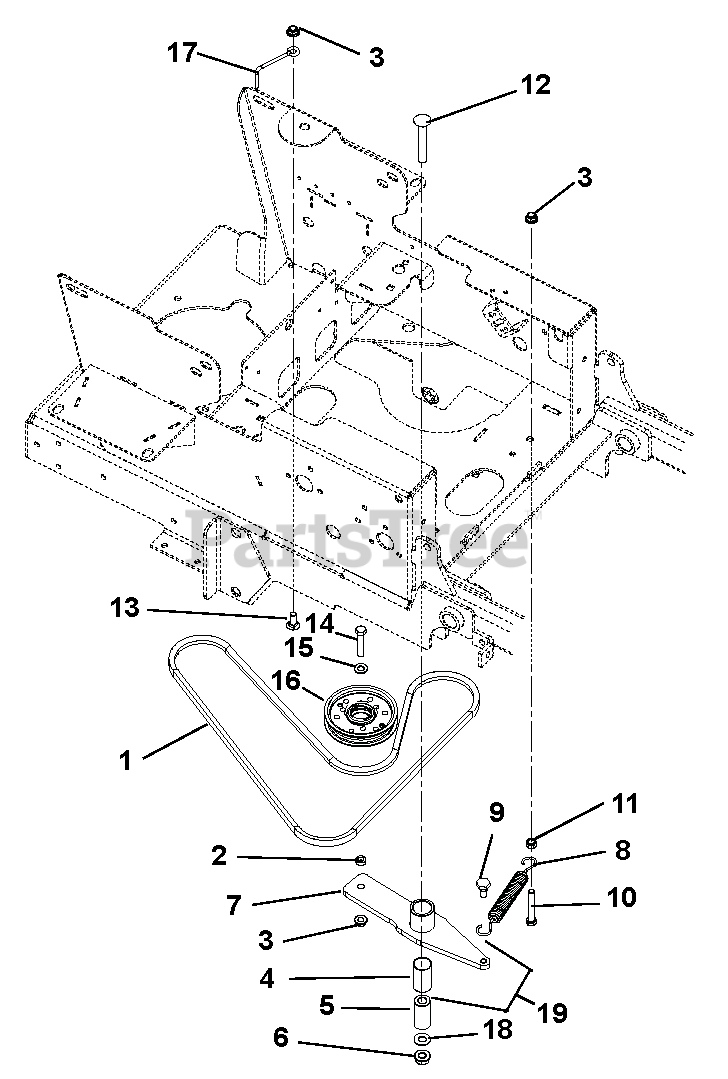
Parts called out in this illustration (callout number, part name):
1	V-BELT, 4L-WRAPPED
2	WSHR-FL-STL .406X1.375X.135 YZ
3	@NUT-LK-NYL-FLG .38-16 YWZC
4	BSHG, 1.00 X 1.125 X 1.937
5	BSHG, SPCR .502X.997X2.03 PM
6	@NUT-LK-NYL-FLG .50-13 YWZC
7	HYDRO DRIVE IDLER ARM WMT -BLK
8	SPRING, EXTENSION
9	BLT,SHLDR EP .38-16X.30 HEX YZ
10	@BLT-HEX .38-16X2.50 GR5 YWZC
11	@NUT-HEX .38-16 YWZC
12	@BLT-HEX .50-13X3.25 GR5 YWZC
13	@BLT-RDHDSQNK .38-16X1.00 G5YZ
14	@BLT-HEX .38-16X2.00 GR5 YWZC
15	@WSHR-FL-STL.406X.812X.065 YWZ
16	ASM, 4" IDLER (.75 WIDE)
17	BELT FINGER
18	WSHR-FL-STL.511X1.441X.125 YWZ
19	ASM, IDLER PIVOT ARM (HYDRO)
